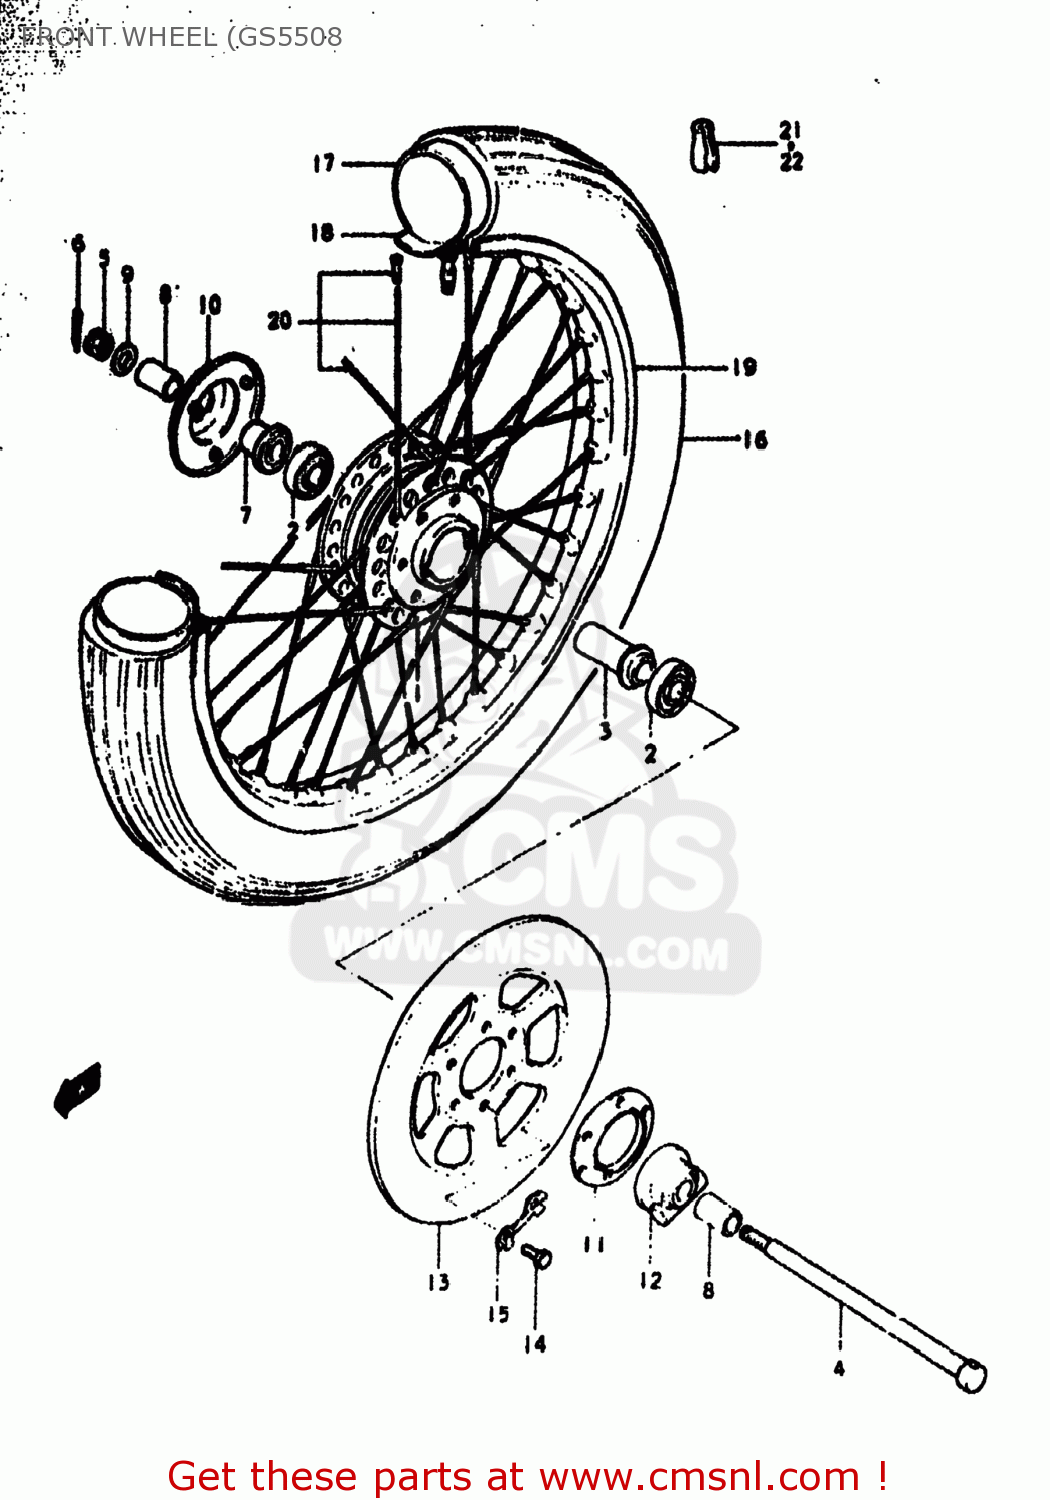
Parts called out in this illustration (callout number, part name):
1	DRUM,FRONT HUB
2	BEARING
3	SPACER,FR HUB BEARING
4	AXLE,FRONT
5	NUT 12MM
6	COTTER PIN
7	SPACER,FR AXLE,R
8	SPACER(15X22X30)
9	WASHER
10	COVER,FR HUB,R
11	DUST SEAL
12	BOX ASSEMBLY,SPEEDOMETER GEAR
13	DISC,BRAKE
14	BOLT(8X30)
15	WASHER
16	TIRE,FRONT
17	TUBE,INNER
18	PROTECTOR,WHL INR TUBE
19	RIM,FR WHEEL
20	SPOKE SET,FRONT
21	BALANCER,WHEEL (B)
22	BALANCER,WHEEL (30G)
